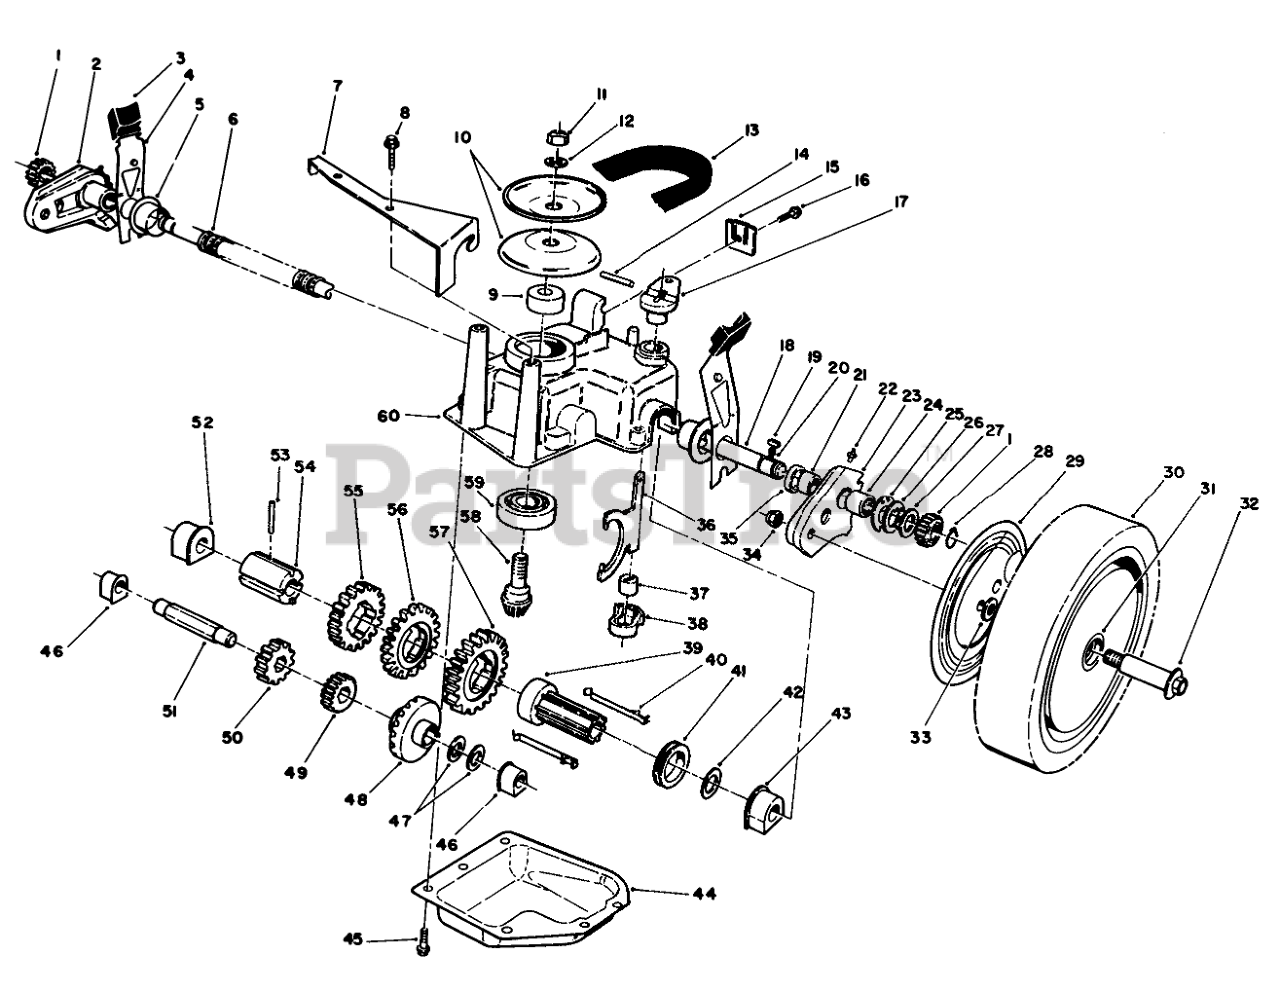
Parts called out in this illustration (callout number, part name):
1	GEAR-PINION
2	Pivot Arm Assembly-R.H. (Incl. Ref. #21, 22, 24 & 35)
3	KNOB-ARM
4	SPRING ARM ASM SP
5	CAP-END
6	CONDUIT-CONVOLUTED, SPLIT
7	Bracket-Guide
8	SCREW-HWHTF
10	Pulley Half
11	NUT-HEX
12	WASHER-FLAT
13	V-BELT E
14	PIN-COIL
15	Cable Clamp
16	SCREW-HWHTF
17	SHIFT LEVER
18	Output Shaft
19	KEY RECTANGULAR
20	SPRING-COMPRESSION
21	BUSHING
22	FITTING-GREASE
23	Pivot Arm Assembly-L.H. (Incl. Ref. #21, 22, 24 & 35)
24	BEARING-ROLLER
25	INNER THRUST WASHER
26	WASHER-THRUST, OUTER
27	WASHER-THRUST, OUTER
28	PIN-ROLL
29	WHEEL COVER
30	Wheel-Tire & Gear Assy. (Incl. Ref. #31)
31	BUSHING
32	WHEEL BOLT
33	WASHER
34	Nut
35	SEAL-OIL
36	YOKE-SHIFT
37	BUSHING-YOKE
38	RETAINER-FORK, SHIFT
39	Sleeve-Shift Key
40	Key Shift
41	SHIFT COLLAR
42	WASHER-PLAIN
43	BUSHING-OUTPUT
44	Cover-Gearcase
45	SCREW-HWHTF
46	BUSHING
47	WASHER-THRUST
48	Gear-Bevel
49	PINION-20T
50	PINION-25T
51	SHAFT-INTERMEDIATE
52	BUSHING
53	PIN-SPRING
54	SLEEVE-GEAR
55	GEAR-39T
56	GEAR-44T
57	GEAR-49T
58	Gear-Pinion
59	BEARING-BALL
60	CASE-GEAR, UPPER
